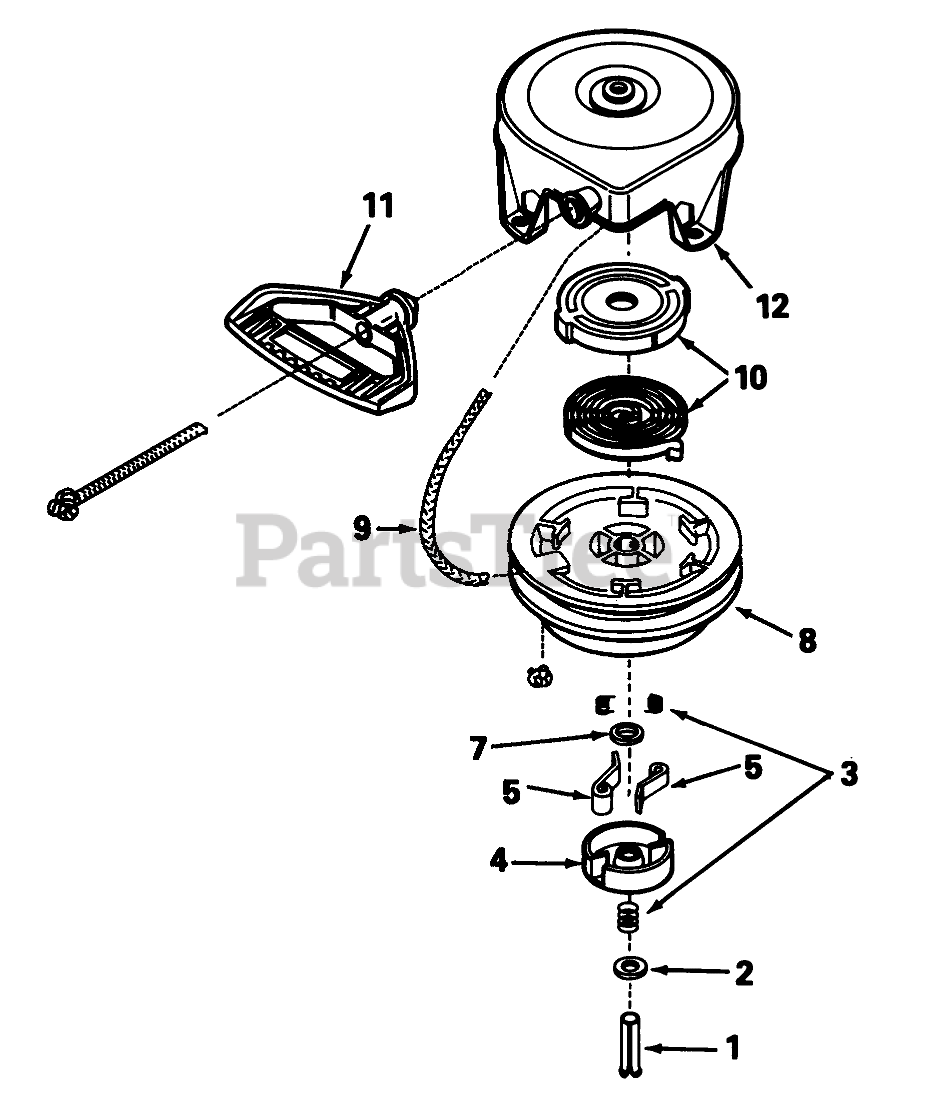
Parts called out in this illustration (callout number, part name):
1	Spring Pin ASM
3	Spring Assembly
4	Retainer
5	Dog-Starter
9	Rope, Starter
10	Spring & Keeper Assy.
11	Handle-Starter, Mitten Grip
12	Housing Assy., Starter
